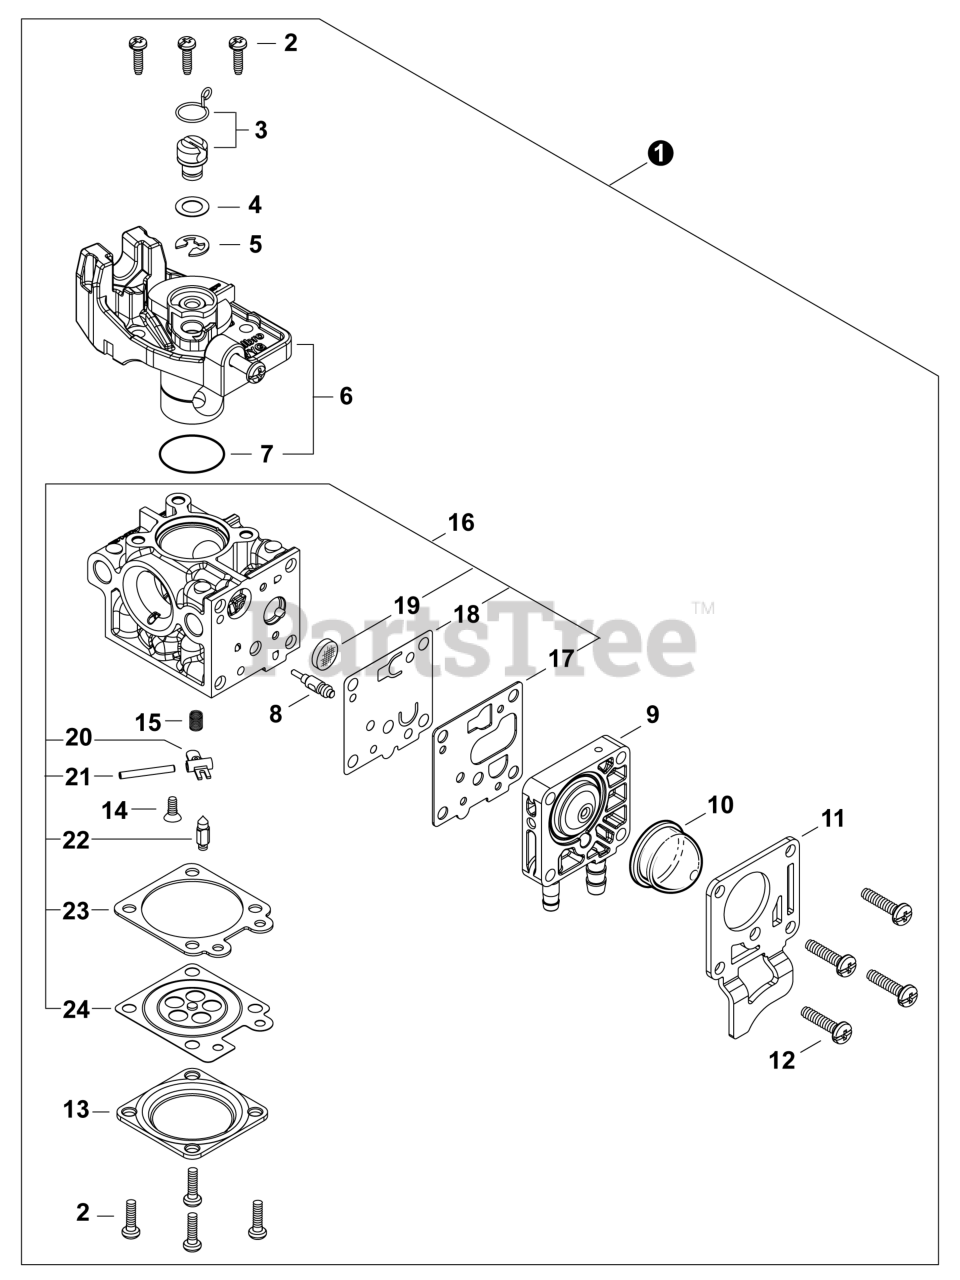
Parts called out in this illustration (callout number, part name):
1	CARBURETOR - WYG-23A
2	SCREW
3	SWIVEL KIT
4	WASHER
5	E-RING
6	THROTTLE VALVE ASSY
7	O-RING
8	NEEDLE, MIXTURE
9	BODY ASSY, PUMP
10	BULB, PURGE
11	COVER, FUEL PUMP
12	SCREW
13	COVER, METERING DIAPHRAGM
14	SCREW
15	SPRING
16	REPAIR KIT, CARBURETOR
17	GASKET, FUEL PUMP
18	DIAPHRAGM, FUEL PUMP
19	SCREEN, FUEL INLET
20	LEVER, METERING
21	PIN, METERING LEVER
22	VALVE, INLET NEEDLE
23	GASKET, METERING DIAPHRAGM
24	DIAPHRAGM, METERING
